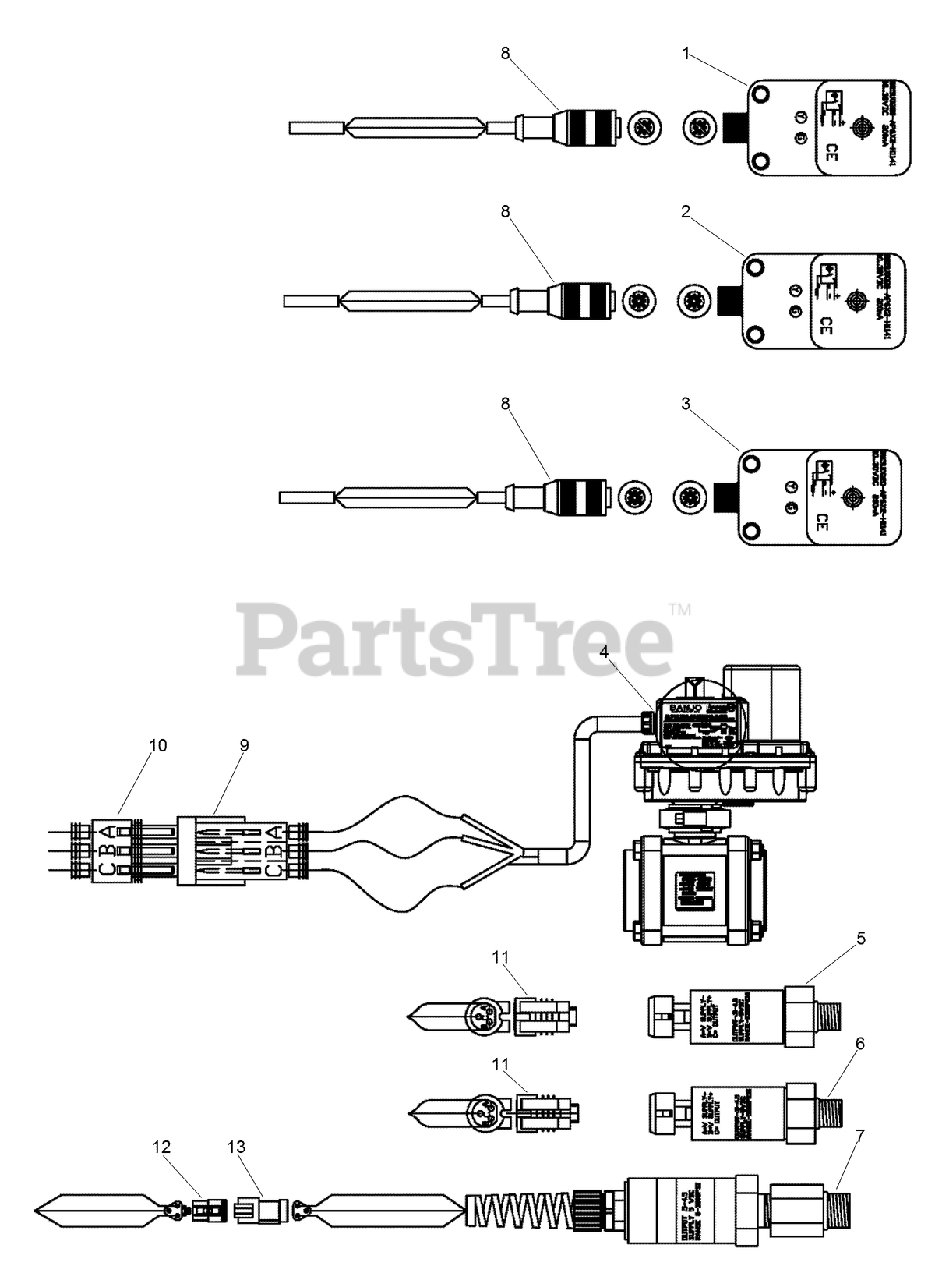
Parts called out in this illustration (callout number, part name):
1	SWITCH-PROXIMITY
2	SWITCH-PROXIMITY
3	SWITCH-PROXIMITY
4	2 INCH BALL VALVE ASM (ELECTRIC)
5	TRANSDUCER - 3300 PSI, 7/16 - 20 SAE
6	TRANSDUCER - 5300 PSI, 7/16 - 20 SAE
7	TRANSDUCER - 3300 PSI, 9/16 - 18 SAE
8	CORD SET - 4 Pin
9	CONNECTOR ASSEMBLY
10	CONNECTOR - 3 Socket
11	PLUG ASSEMBLY - 8EP78221 and 8EP78222 Transducers
12	PLUG ASSEMBLY - 8EP78223 Transducer
13	RECEPTACLE ASSEMBLY - 3 Pin
